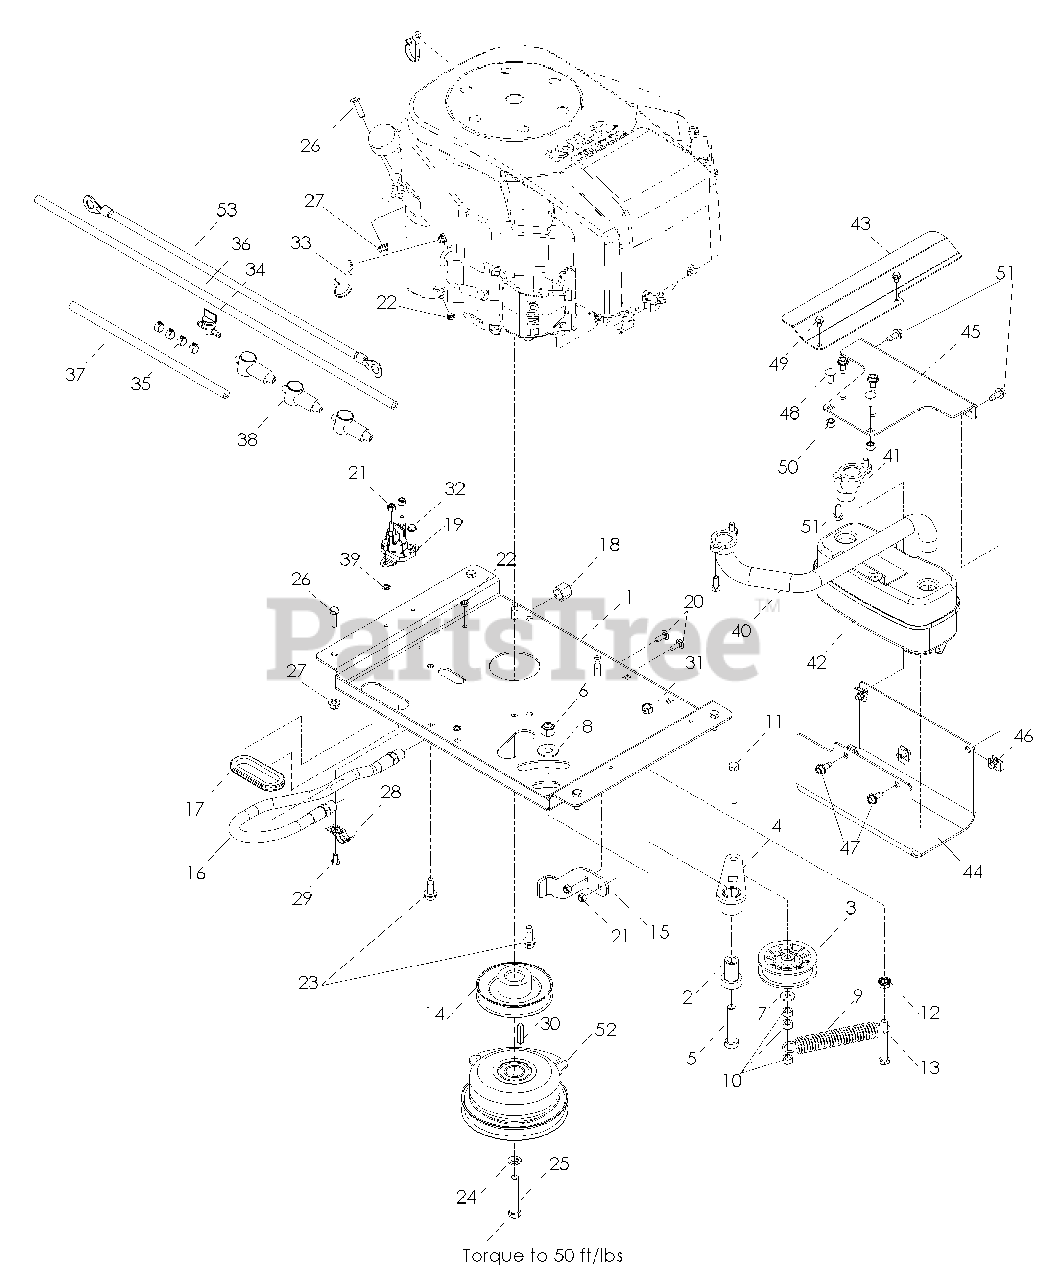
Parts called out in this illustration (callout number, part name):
1	PLATE, ENGINE
2	IDLER SPINDLE
3	PULLEY, IDLER
4	IDLER ARM WELDMENT
5	HEX SCREW 1/2-13 X 2.5" GR 5
6	NUT 1/2-13 HEX NYLOC ZD
7	WASHER 5/16 FLAT
8	WASHER 1/2 FLAT
10	NUT 3/8-16 NYLOC
11	HCS 3/8-16 X 2-1/2 TPBLT
12	NUT 3/8C WHIZ
13	SCREW 3/8C X 2 3/4 HEX CAP
15	TIE DOWN, CLUTCH
16	DRAIN, OIL
17	GROMMET
18	DRAIN CAP
19	SOLENOID
20	RHSNB 1/4C X 3/4
21	NUT 1/4-20 NYLOC
22	JAM NUT 1/4C
23	BOLT 3/8-16 X 1.0
24	WASHER 7/16 LOCK
25	BOLT 7/16F X 2 1/2
26	HCS 5/16C X 1
27	5/16-18 NYLOC FLANGE NUT
29	HCS 1/4-20.
30	KEY, 1/4 SQ X 1 1/4
31	NUT 3/8C CENTERBLOCK
32	HWST 1/4C X 3/8
34	FUEL VALVE
35	HOSE CLAMP
36	FUEL LINE 30"
37	FUEL LINE 13"
38	INSULATOR
39	WASHER 1/4 INT TOOTH
40	MANIFOLD, FT
41	MANIFOLD, RR
42	MUFFLER ASM TWIN
43	SHIELD, HEAT
44	GUARD, MUFFLER
45	MOUNT MUFFLER BLACK
46	U-CLIP 5/16-18 NUT RETAINER
47	BOLT 5/16-18 X 3/4
48	BOLT 5/16C X 3/4" CARRIAGE
49	HWST 1/4C X 3/8
50	NUT 5/16 NYLOC
51	HCS 5/16C X 3/4
52	CLUTCH, 200 FT/LB
52	CLUTCH, 125 FT/LB
53	CABLE, POSITIVE
